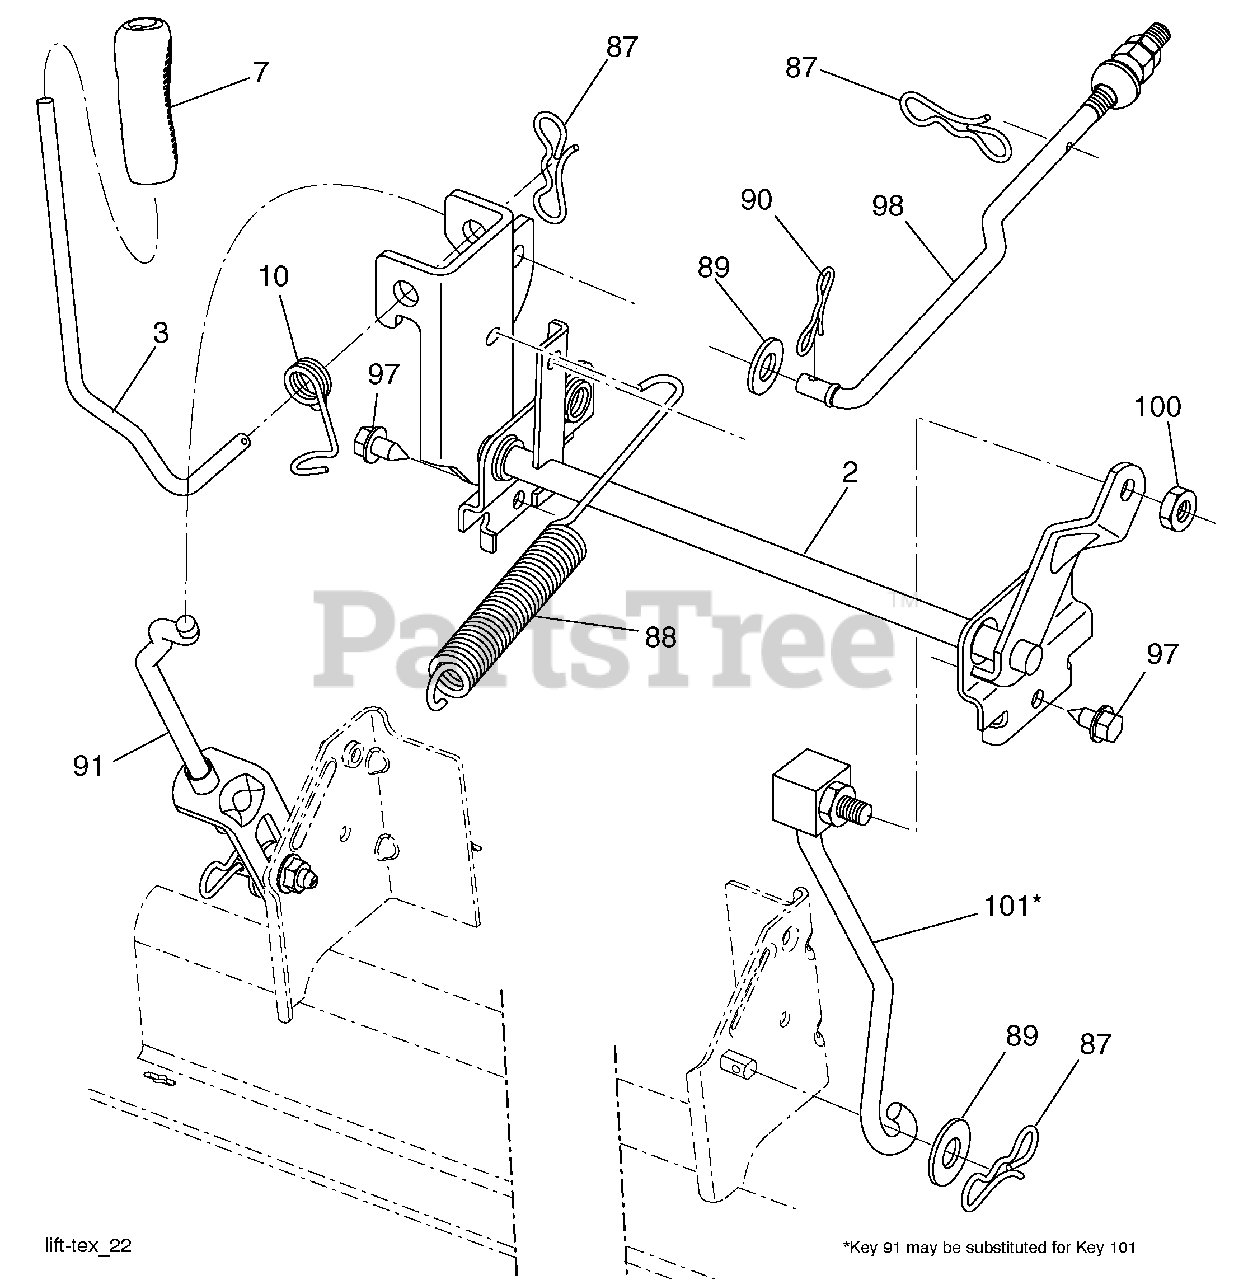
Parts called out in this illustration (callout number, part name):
2	Shaft Asm., Lift
3	Lever Asm., Lift RH
7	Grip, Lever
10	Spring Torsion
87	Pin Cotter 7/16 Bow Tie Lock
88	Spring Lift Assist
89	Washer Clear Zinc
90	Pin Cotter 5/16 Bow Tie Lock
91	Link Asm Lift LH Rear
97	Screw Hex Wsh. THDR 3/8-16 x 3/4
98	Link Lift Susp. Front Mower
100	Nut Centerlock 3/8-16 unc
101	Link Asm. Lift FXD
